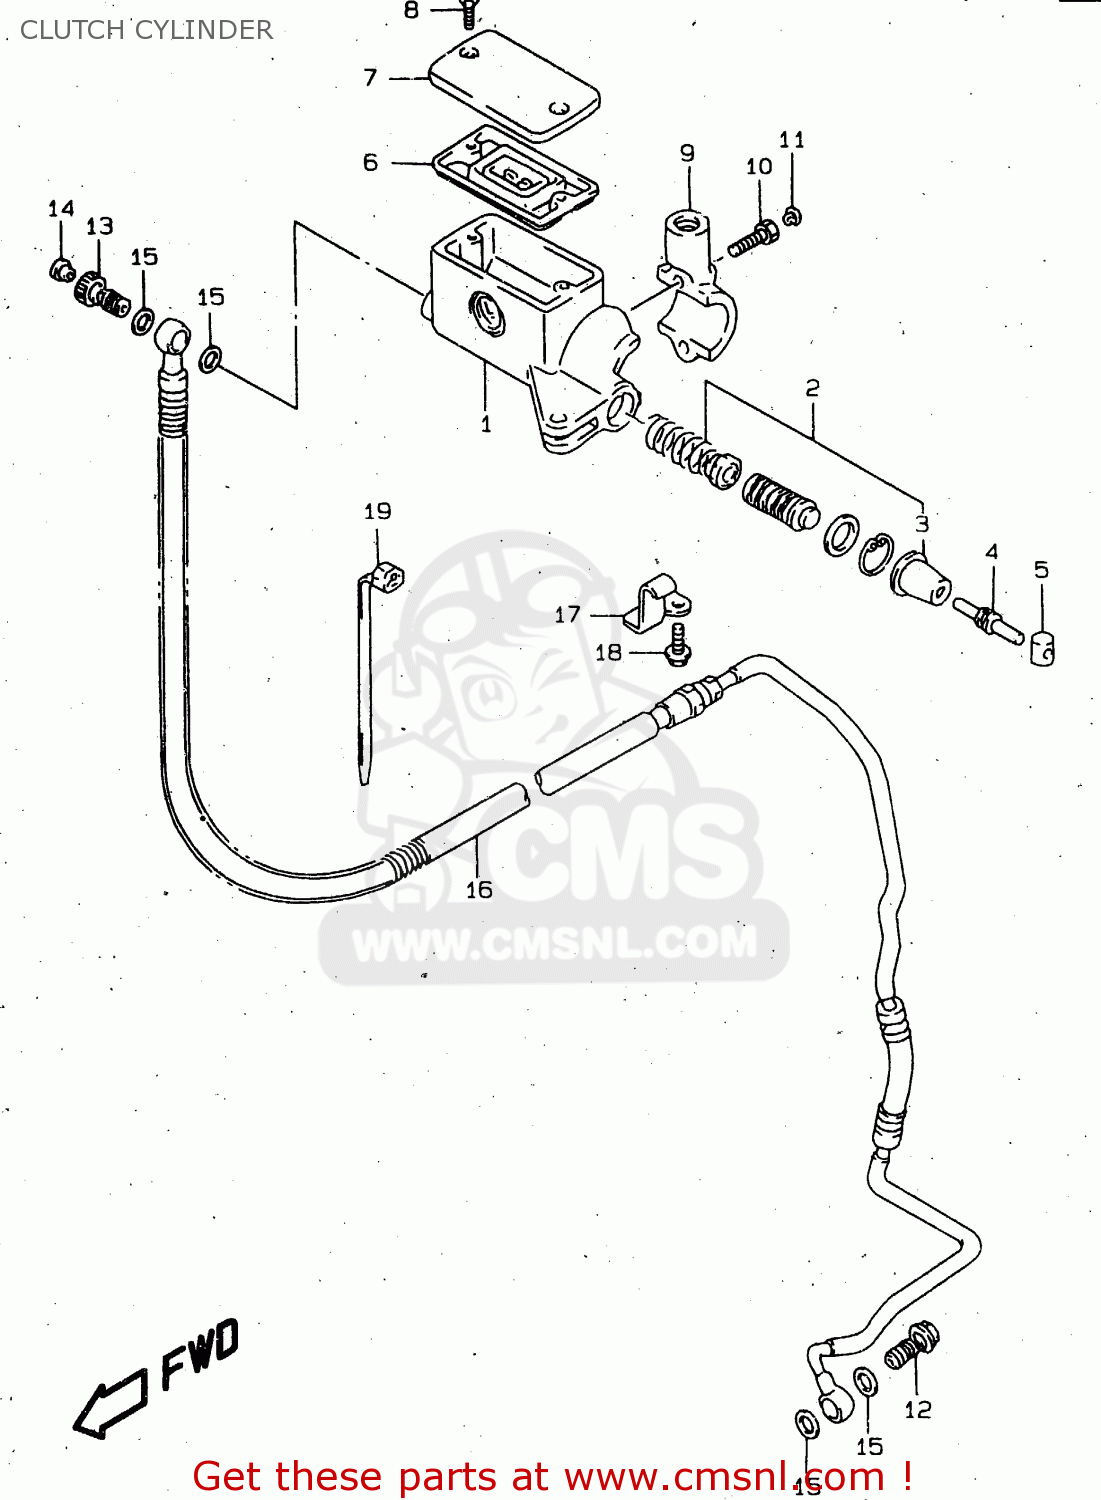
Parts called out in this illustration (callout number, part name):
1	CYLINDER ASSEMBLY,CLUTCH MASTER
2	PISTON & CUP SET
3	BOOT
4	PUSH ROD
5	BUSH
6	7
7	CAP
8	SCREW
9	HOLDER
10	BOLT
11	CAP(OD:10)
12	BOLT UNION
13	BOLT UNION
14	CAP(OD:12)
15	WASHER(10X15X1.5)
16	HOSE ASSY,CLUTCH
17	CLAMP,CLUTCH HOSE
18	BOLT
19	CLAMP(L:165)
